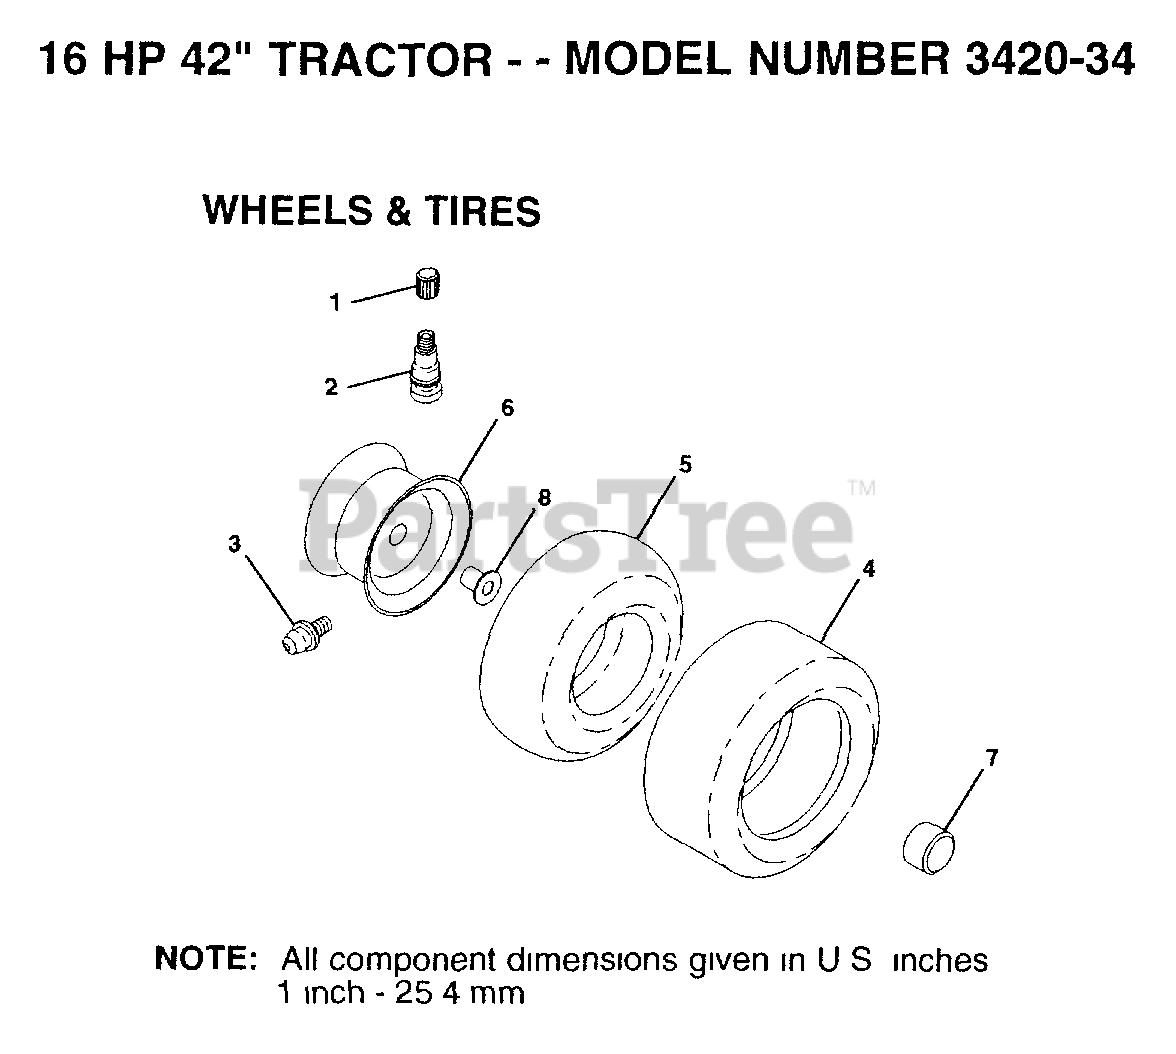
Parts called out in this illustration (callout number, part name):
1	VALVE CAP
2	VALVE STEM LT
3	FITTING LT
4	TIRE.20X8-8
5	TUBE.5.3/4.5/6
5	TUBE.18X9.5-8
7	HUB CAP
8	"FLANGE, BEARING"
